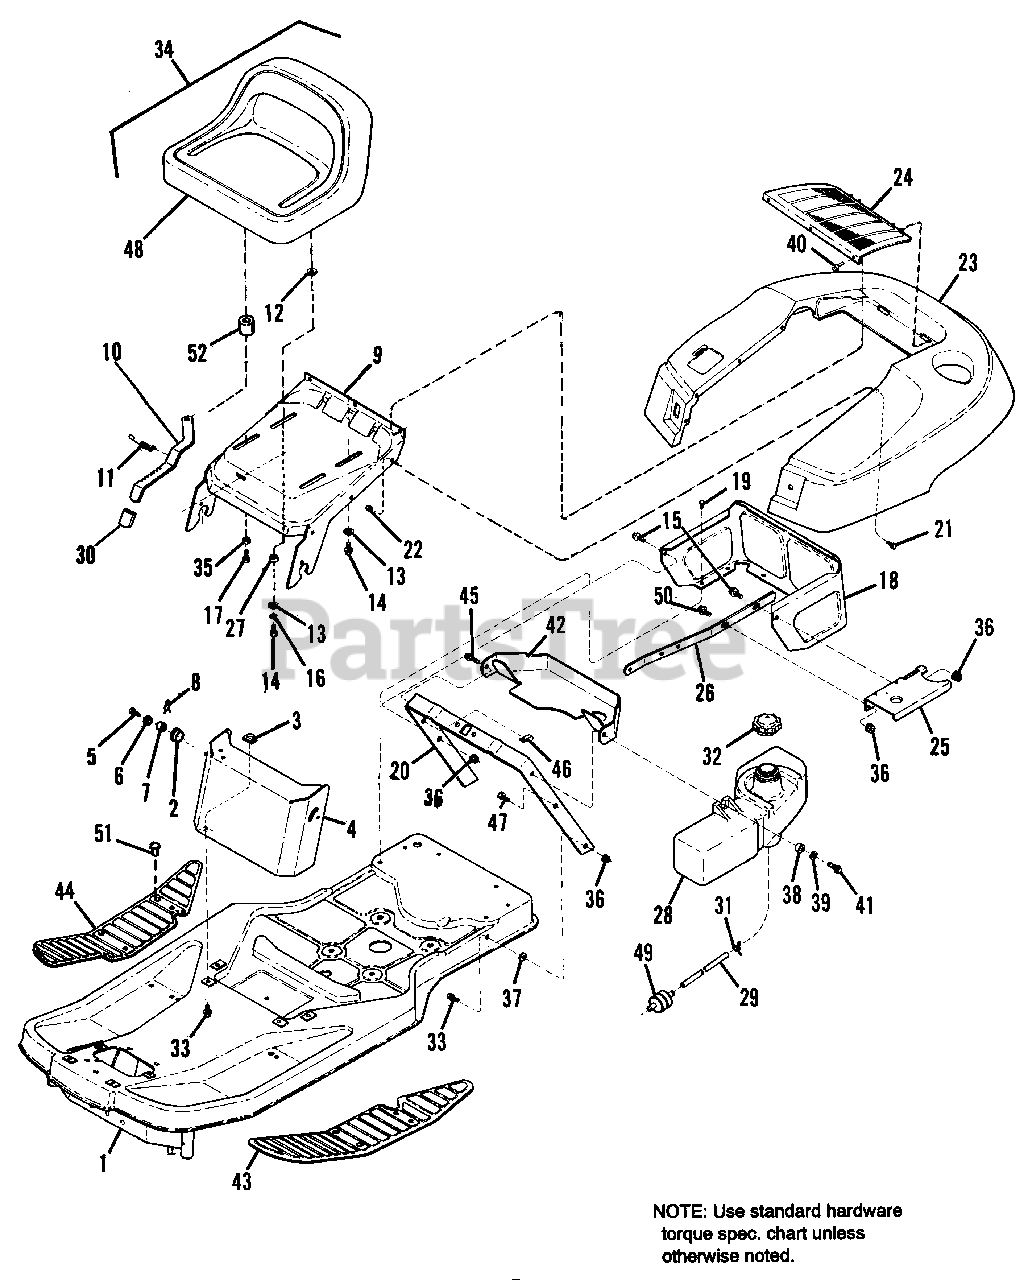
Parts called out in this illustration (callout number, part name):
1	FRAME ASSY.
3	PAL NUT, 5/16-18
4	PANEL, Front
5	SCREW, Taptite, 5/16-18 x 1
6	PIVOT, Hood
7	SPACER, Hood
8	CLIP, Hairpin
9	SUPPORT, Seat
10	ADJUSTER, Seat
12	SPACER, Seat Side
13	WASHER, Plain, 11/32 x 1 x 1/8
14	CAPSCREW, Hex Hd., Whizlock, 5/16 x 5/32 x 5/8
15	CAPSCREW, Hex Hd., 5/16-18 x 3/4
16	LOCKWASHER, 5/16
17	CAPSCREW, Hex Hd., 5/16-18 x 1-1/4
18	SHROUD, Rear
19	SCREW, Hex Hd., Taptite, 1/4-20 x 1/2
20	SUPPORT, Seat Deck
21	CAPSCREW, Hex Hd., 1/4-20 x 5/8
22	NUT, Hex, Flange Lock, 1/4-20
23	DECK, Seat
24	SCREEN
25	SUPPORT, Fuel Tank
26	STRAP, Fuel Tank, Brace
28	FUEL TANK (Includes Ref. No. 49)
29	HOSE, Fuel Tank
30	CAP, Vinyl, Black
31	CLAMP, Hose
32	CAP, Fuel Tank, Vented
33	SCREW, Hex Hd., Whizlock, 5/16-18 x 3/4
34	SEAT ASSY. (Includes Ref. No. 48)
35	NUT, Hex, 5/16-18
36	NUT, Hex, Flange, Whizlock, 5/16-18
37	PAL NUT, 5/16
38	SPACER, 21/64 x 1/2 x 21/64
39	WASHER, Plain, 13/32 x 7/8 x 5/64
41	SCREW, Hex, Washer Hd., Tap, 5/16-18 x 1
42	DUCT, Air Inlet
43	PAD, Foot Rest, L.H.
44	PAD, Foot Rest, R.H.
45	SCREW, Hex Hd., Taptite, 5/16 x 1/2
46	CLIP
47	CAPSCREW, Hex Hd., 5/16-18 x 1
48	COVER, Seat
49	FUEL FILTER
50	CARRIAGE BOLT, 5/16-18 x 3/4
